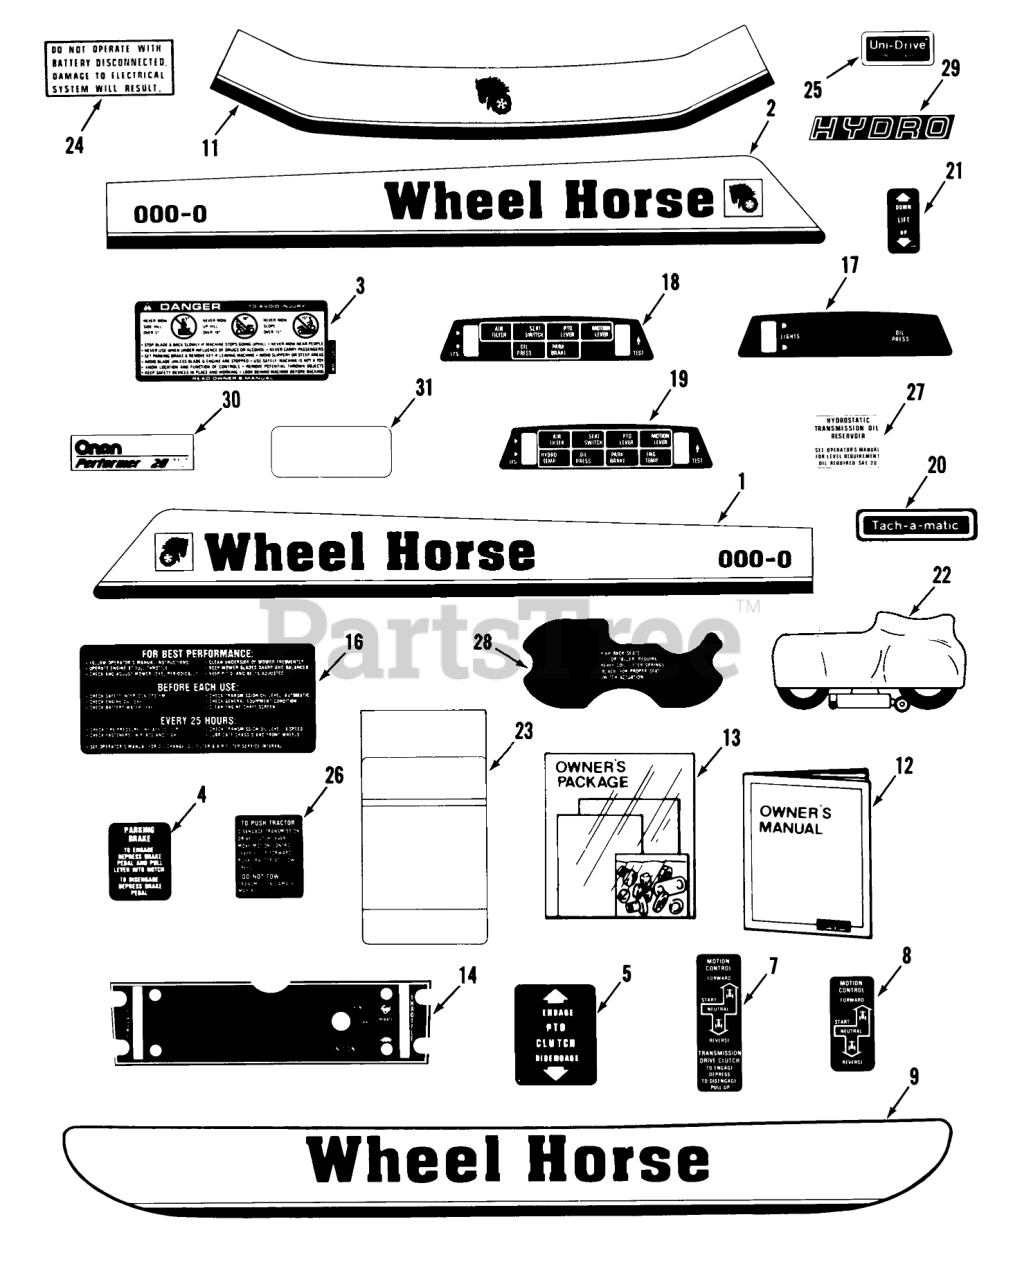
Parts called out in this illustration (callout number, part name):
1	DECAL-HOOD R.H.
1	Decal-Hood RH 518-H (31-18OE01)
1	DECAL-HOOD 518-H R H
1	Decal-Hood RH 520-H (31-20OE01)
1	DECAL-HOOD 520-H R H
1	Decal-Hood RH 520-HC (C1-20OE01)
1	DECAL-HOOD 520-HC RH
2	DECAL-HOOD L.H.
2	Decal-Hood LH 518-H (31-18OE01)
2	DECAL-HOOD 518-H L H
2	Decal-Hood LH 520-H (31-20OE01)
2	Decal-Hood LH 520-H (31-20OE02)
2	Decal-Hood LH 520-HC (C1-20OE01)
2	DECAL-HOOD 520-HC LH
3	DECAL-DANGER
4	DECAL-PARKING, BRAKE
5	DECAL PTO CLUTCH
7	DECAL-MOTION CONTROL
8	DECAL-MOTION CONTROL
9	Decal-Rear Fender
11	Decal-Hood Front
12	Owners Manual-Tractor
13	Loose Parts Package 516-H
13	Loose Parts Package 518-H
13	Loose Parts Package
13	Loose Parts Package 520-HC
14	Decal-Front Panel (31-16OE01, 31-18OE01, 31-20OE01 & C1-20OE10 VINs only)
14	DECAL-FRONT PANEL
16	DECAL-REAR HOOD
17	DECAL-INDICATOR
18	DECAL-INDICATOR LTS
19	DECAL-INDICATOR LTS
20	Decal-Tach-a-matic
21	DECAL-LIFT
22	Vinyl Tractor Cover
23	Decal-Maintenance
24	DECAL ELECT SYSTEM
25	Decal-Unidrive
26	DECAL-TO PUSH TRACT
27	DECAL-TRANS OIL
28	DECAL-SEAT LIFTER
29	DECAL-HYDRO
30	Decal-Performer 16 HP (vendor #98-5640-02)
30	Decal-Performer 18 HP (vendor #98-5641-04)
30	DECAL PERFORMER 20HP
31	DECAL-OVERLAY
